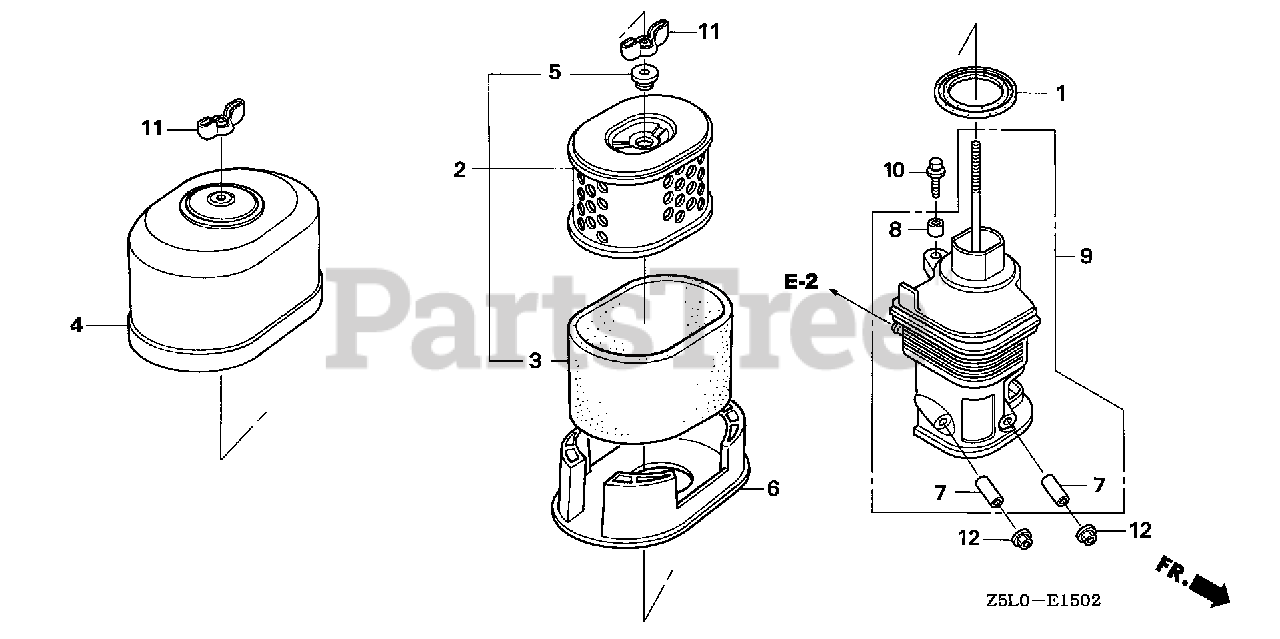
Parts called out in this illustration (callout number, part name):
1	GASKET, ELBOW
2	ELEMENT, AIR CLEANER
3	FILTER (OUTER)
4	COVER, AIR CLEANER (STD)
5	GROMMET, AIR CLEANER
6	NOSE, MUFFLER
7	COLLAR, AIR CLEANER
8	COLLAR B, AIR CLEANER
9	ELBOW, AIR CLEANER
10	BOLT-WASHER (6X22)
11	NUT, TOOL BOX SETTING
12	NUT, FLANGE (6MM)
